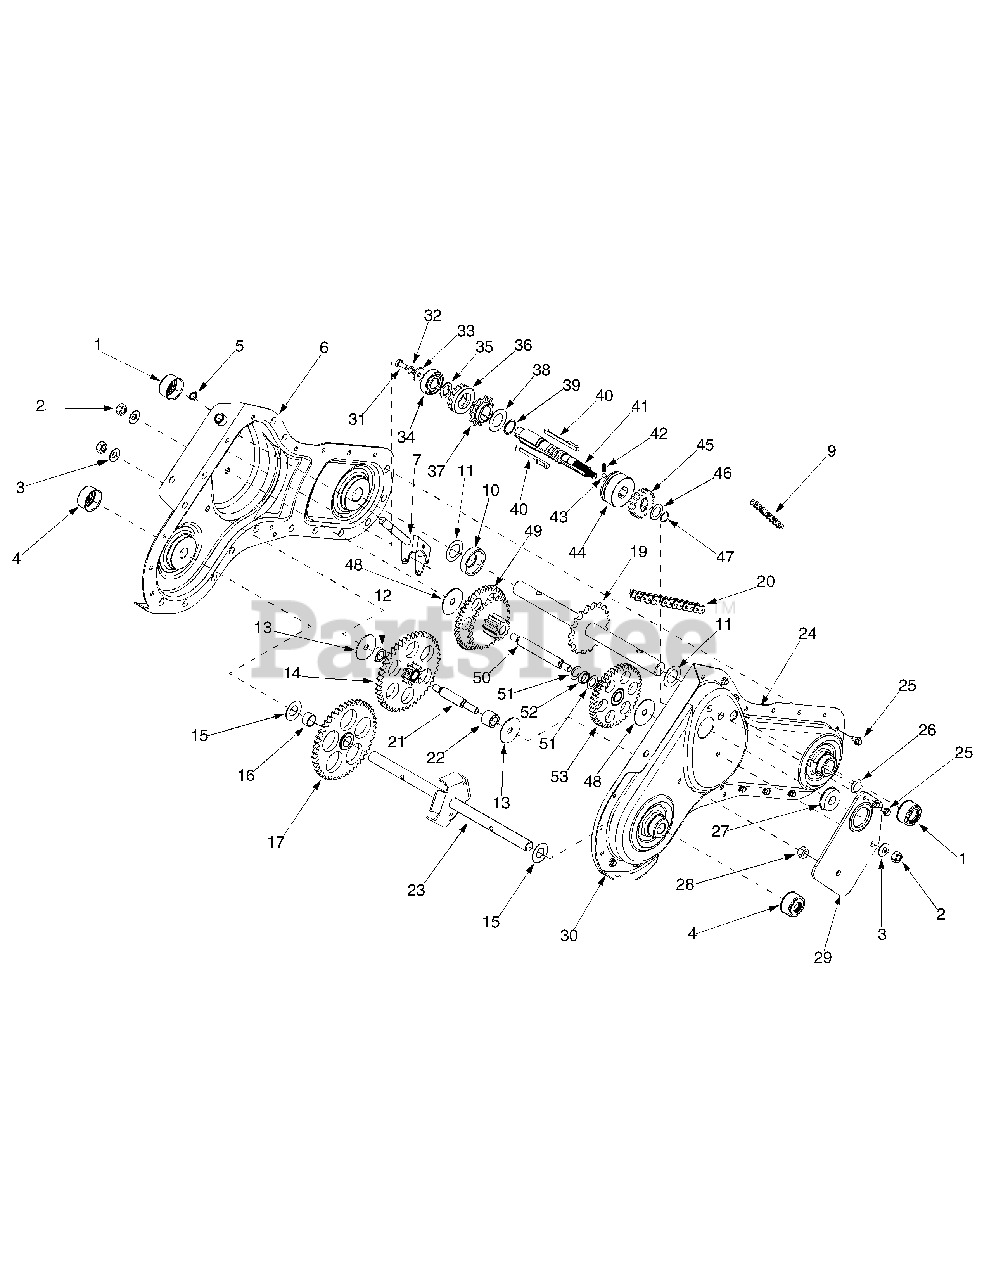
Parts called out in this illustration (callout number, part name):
1	Shaft Seal 1.0 Dia
2	Hex Nut 7/16-20
3	Bell Washer.45 ID x 1.0 OD
4	Shaft Seal.75 Dia
5	Snap Ring.50 Dia
7	Shift Assembly
9	Chain - #41 1/2" Pitch x 30 Links
10	Space 1.0 ID x 2.0 OD
11	Thrust Washer 1.03 ID x 1.62 OD
12	Spacer.635 ID x 1.0 OD
13	Thrust Washer.445 ID x 1.92 OD
14	Idler Gear Assembly
15	Flat Washer.760 ID x 1.50 OD
16	Spacer.735 ID x.886 OD
17	Spur Gear 46T
19	Tine Shaft Assembly 18T
20	Chain - #50 5/8" Pitch x 52 Links
21	Jack Shaft 5/8 Dia. X. 2.06 Lg
22	Spacer.635 ID x 1.0 OD
23	Wheel Shift Assembly
27	Ball Bearing w/Snap Ring
28	Hex Patch L-Nut 7/16-20
30	Chain Case Gasket
31	Hex Cap Screw 1/4-20 x.625
32	Lock Washer 1/4
33	Flat Washer.281 ID x.875 OD
34	Ball Bearing
35	Flat Washer
36	Spur Gear 16T
37	Sprocket 11T #41 Chain
38	Flat Washer.88 ID x 1.50 OD
39	Retainer Ring
40	Clutch Key
41	Drive Shaft
42	Compression Spring
43	Detent Ball
44	Clutch Collar
45	Spur Gear 17T
46	Flat Washer.69 ID x 1.06 OD
47	Wire Ring
48	Thrust Washer.445 ID x 1.9 OD
49	Intermediate Gear Assembly
50	Jack Shaft
51	Flat Washer.625 ID x 1.0 OD
52	Spacer.635 ID x.86 OD
53	Tine Drive Assembly
